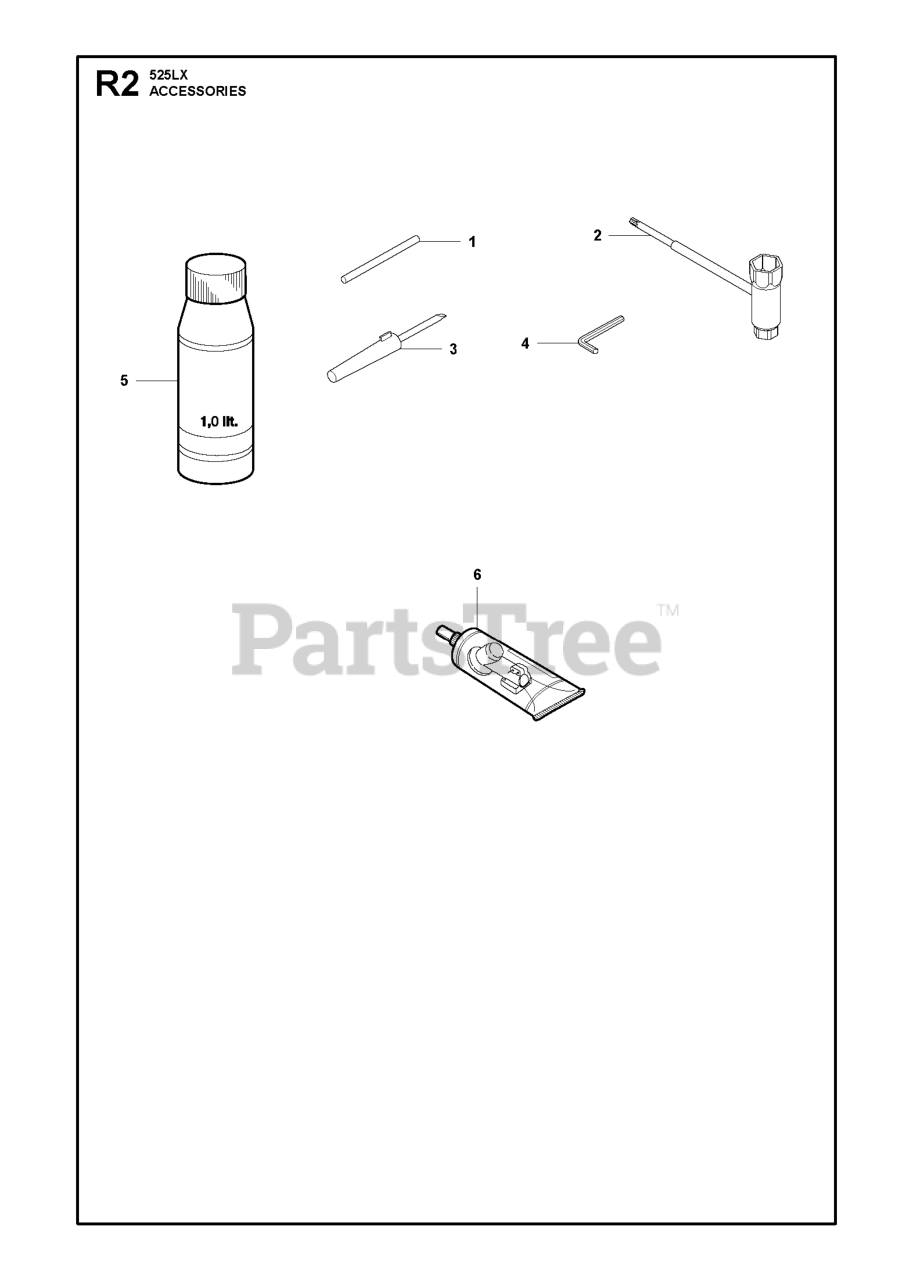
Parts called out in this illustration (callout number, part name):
1	LOCKING PIN
2	COMBINATION WRENCH TORX
3	SCREWDRIVER
5	Air Filter Oil 1l.
6	BEVEL GEAR GREASE
